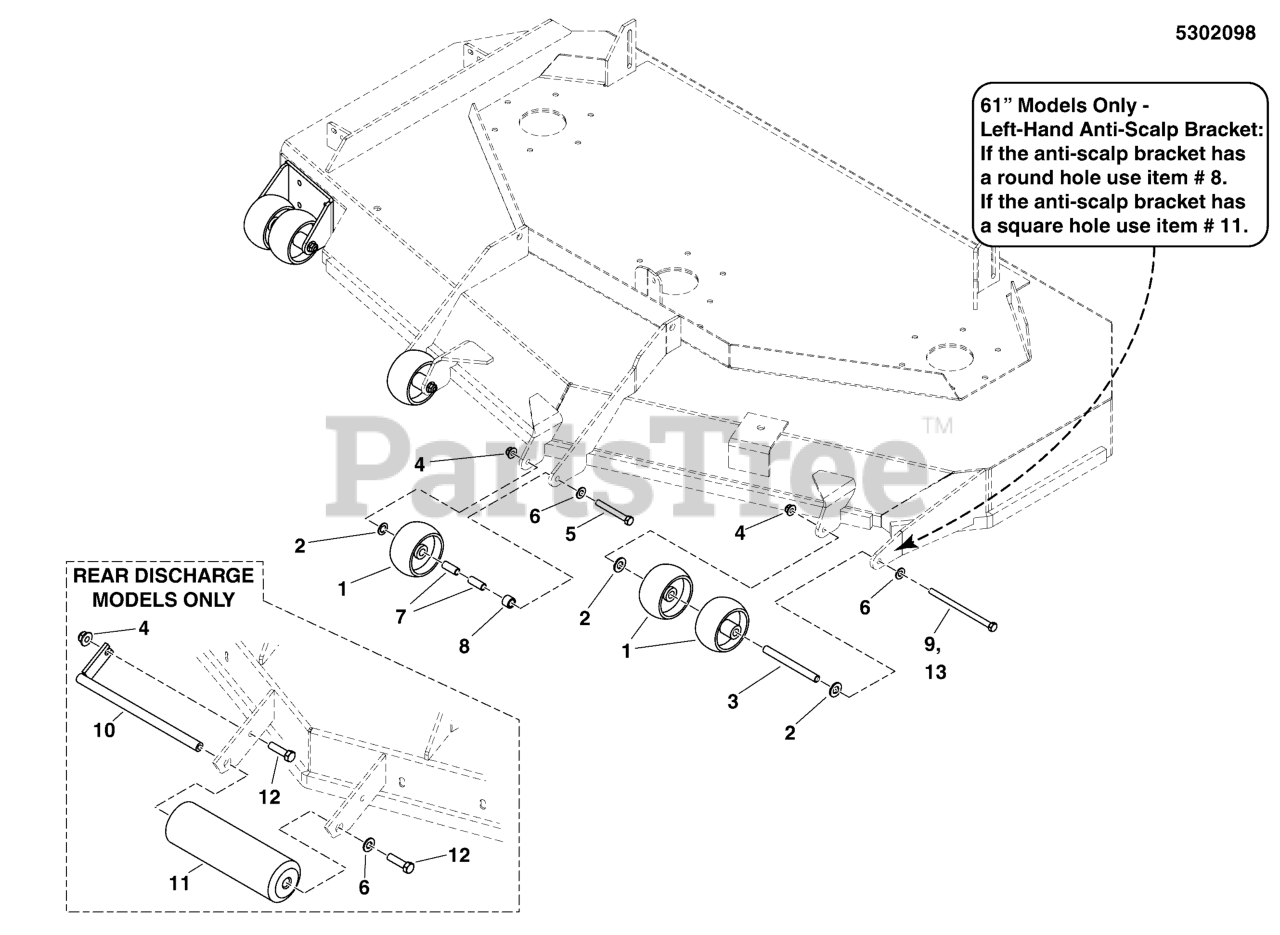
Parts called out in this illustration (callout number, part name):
1	GAUGE WHEEL
2	WASHER, 1/2" GD9 YZ
3	SPACER, .38 X .50 X 5.06
4	NUT, 3/8-16 HEX SIDE LOCK
5	BOLT, 3/8-16 X 3" GD5 CZ
6	WASHER, 3/8 SAE
7	SPACER, .38 X .50 X 1.25, CZ
8	SPACER, .51 X .75 X .56
9	BOLT, 3/8-16 X 6" GD5 CZ
11	ROLLER, DECK
12	BOLT, 3/8-16 X 1" GD5 CZ
13	BOLT, CARRIAGE, 3/8-16X6, GD5, YZ
